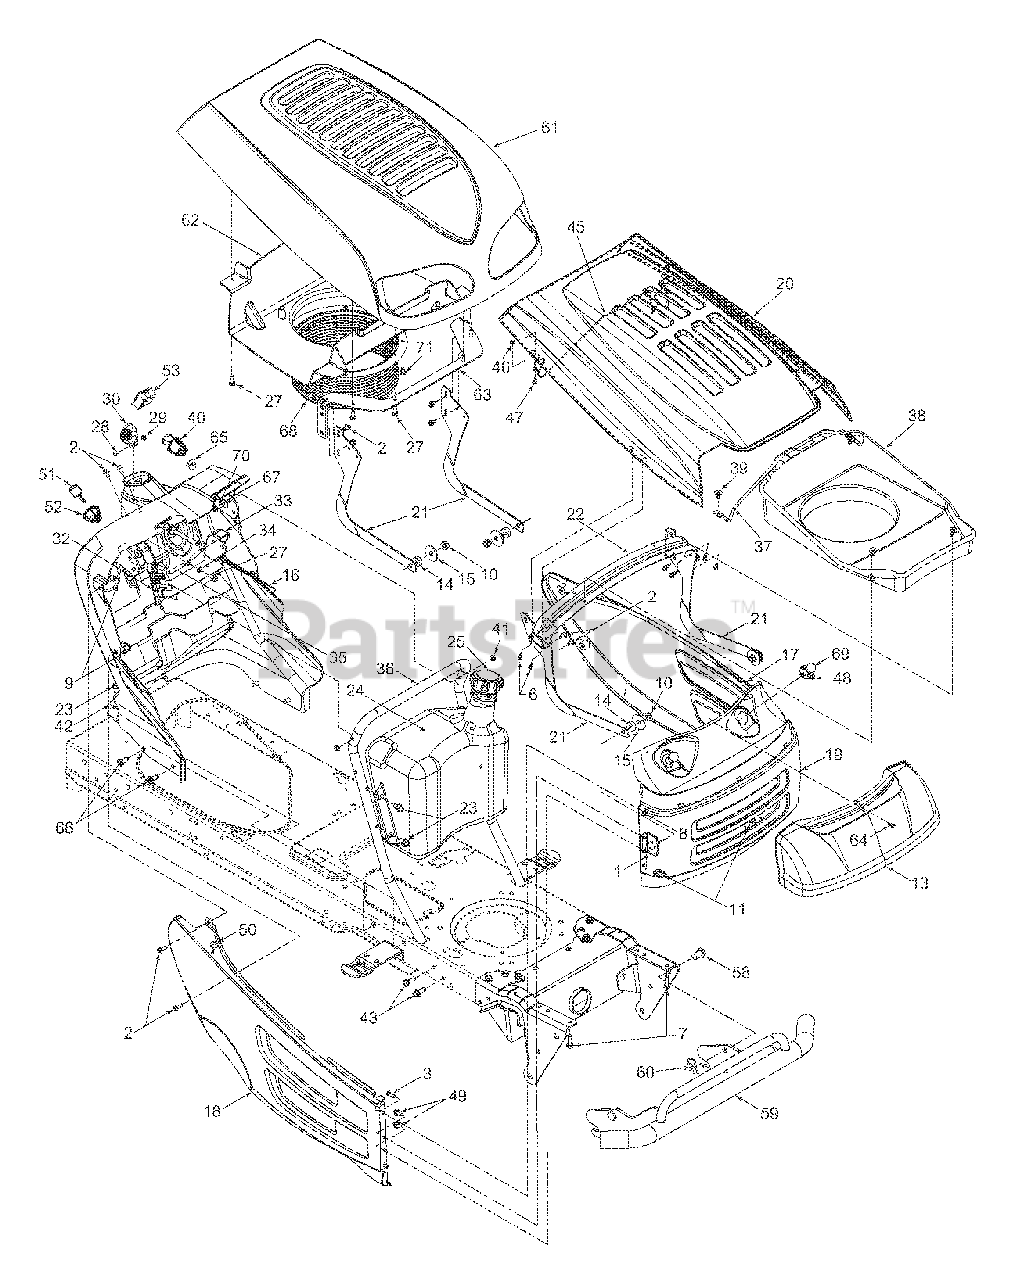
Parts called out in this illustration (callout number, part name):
2	Self-tapping Screw, 1/4-20 x .5
3	Hex Cap Screw, 1/4-20 x .62
6	Screw, #10-16 x .5
7	Hex Cap Screw, 5/16-18 x 1.0
8	Hex Sems Nut, 1/4-20
9	U-type Speed Nut, 1/4-20
10	Flange Lock Nut, 3/8-16
11	U-nut, 5/16-18
13	Headlight Lens (8-style)
14	Rubber Washer, .87 x .33
15	Flat Washer, .406 x 1.5 x 11GA
16	Choke Knob/Cable (Models with any B&S Twin)
24	Fuel Tank, Three Gallon
25	Fuel Cap (Fits Either Tank)
27	Self-tapping Screw, 1/4-15 x .75
28	Truss Phillips Screw, #8-32 x .375
29	Hex Nut, #8-32
30	Throttle Control Knob
32	Cruise Control Button
33	Parking Brake Button
34	Flat Washer, 9/32 x 1/2 x 1/16
35	Brake/Cruise Pivot Rod
38	Hood Plenum (Models with B&S OHV V-Twin)
39	Ratchet Clip
40	Electric PTO Switch
41	Hex Flange Lock Nut, 1/4-20
42	Flat Washer, .349 x 1.0 x .063
43	Screw, 5/16-18 x .875 (Grade 5)
45	Hood Latch
46	Hex Sems Nut, #10-32
47	Machine Screw, #10-24
48	Headlight Socket
49	Hex Index Washer Screw, 1/4-14 x .0625
50	Rubber Bumper
51	Ignition Key w/ plastic cover
52	Ignition Switch
53	Systems Indicator Monitor w/ Hour Meter
58	Clevis Pin, .50 x .78
59	Bumper Assembly
60	Internal Cotter Pin
61	Hood, Red (7-Style)
62	Hood Plenum
65	Choke Plug
66	Screw, 5/16-18 x .75
67	Bell Washer, .265 x .75 x .062
68	Intake Bellow (Intek Single & kohler)
69	Lamp
70	Self-tapping Screw, 1/4-20 x .75
71	Self-tapping Screw, 1/4-20 x .50
